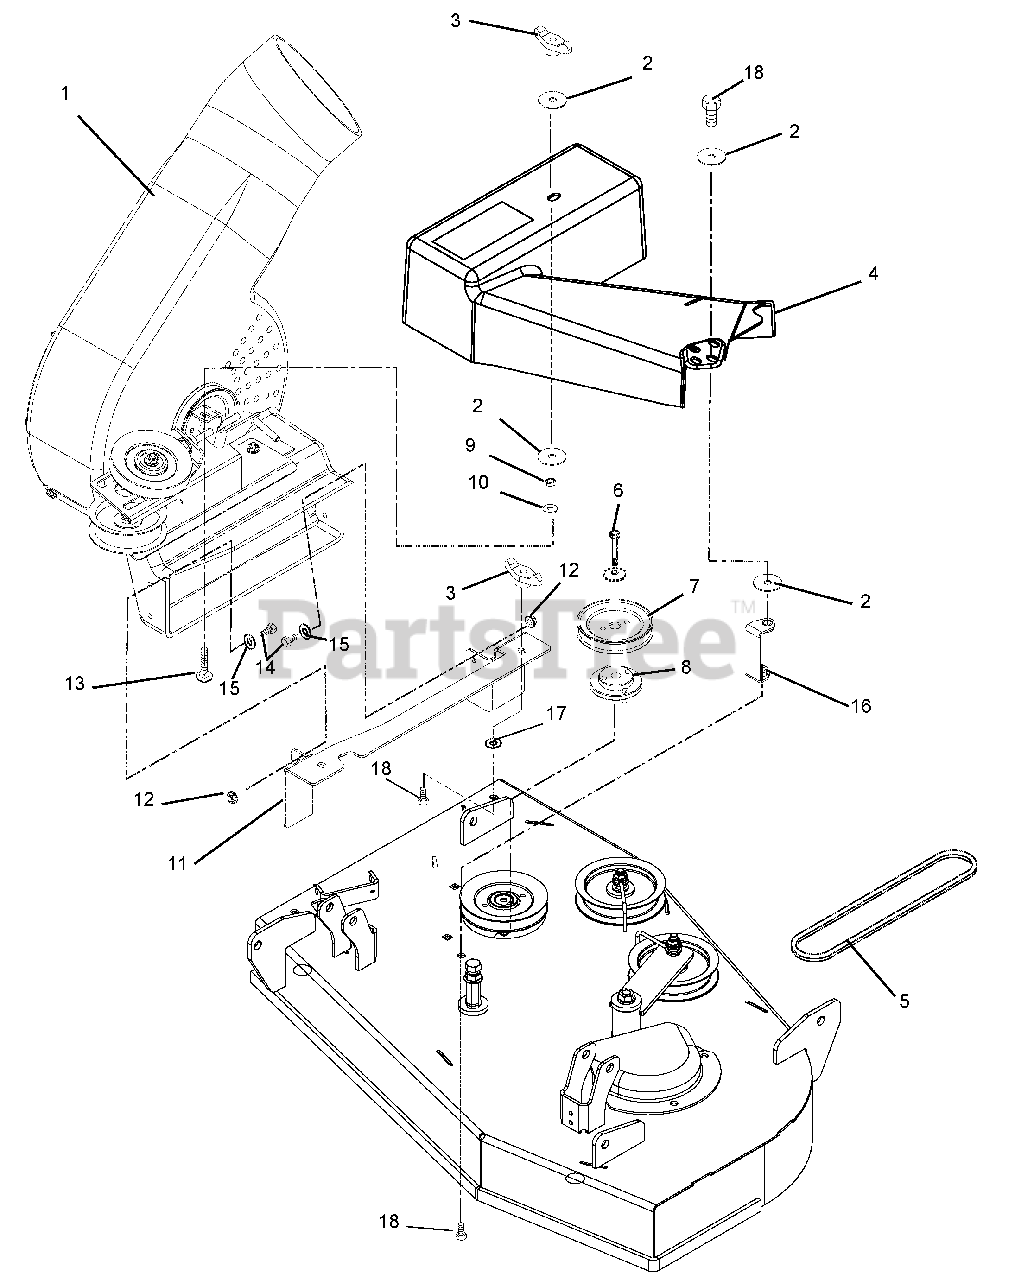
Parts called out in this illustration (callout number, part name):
1	Housing, Blower
2	Washer, Flat, Steel.38 x 1.50 x .062
3	Knob, Wing .312-18
4	Belt Cover, 34-Inch
5	4L V-Belt, 34-Inch Blower
6	Bolt-Hex .38-16 x 1.75 – Grade 8
7	Sheave, 4.00 Diameter
8	Assembly, Sheave Adapter
9	Nut, Jam .312-18
10	Washer, Flat, Steel .312 x .734 x .065
11	Weldment, Blower Bracket (34-Inch)
12	Nut, Locking-Top-Flange .25-20
13	Bolt, Round Head Square Neck .31-18 x 1.50
14	Bolt, Hex .25-20 x 1.00 Grade 5
15	Washer, Flat, Steel .281 x .62 x .065
16	Cover Spacer
17	Push Nut
18	Bolt, Hex 3/8" x 1"
